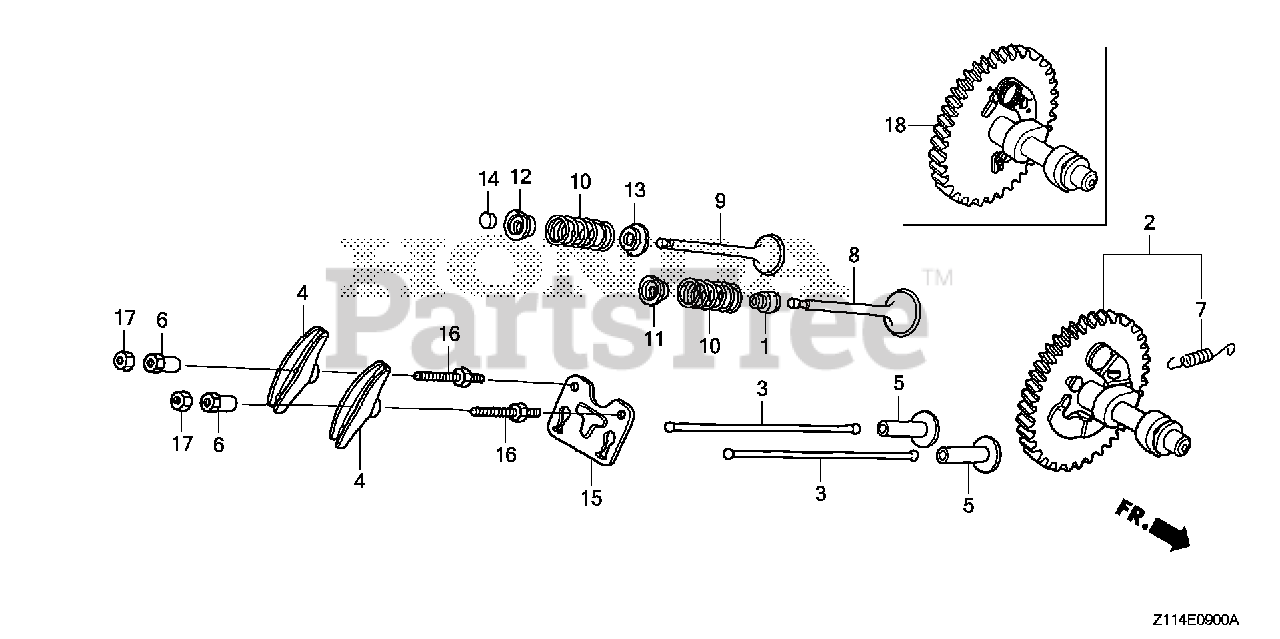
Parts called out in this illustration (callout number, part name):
1	SEAL, VALVE STEM
2	CAMSHAFT ASSY.
3	ROD, PUSH
4	ARM, VALVE ROCKER
5	LIFTER, VALVE
6	PIVOT, ROCKER ARM
7	SPRING, WEIGHT RETURN
8	VALVE, IN.
9	VALVE, EX.
10	SPRING, VALVE
11	RETAINER, IN. VALVE SPRING (EXHAUST SIDE)
12	RETAINER, EX. VALVE SPRING
13	SEAT, VALVE SPRING
14	ROTATOR, VALVE
15	PLATE, PUSH ROD GUIDE
16	BOLT, PIVOT (8MM)
17	NUT, PIVOT ADJ.
